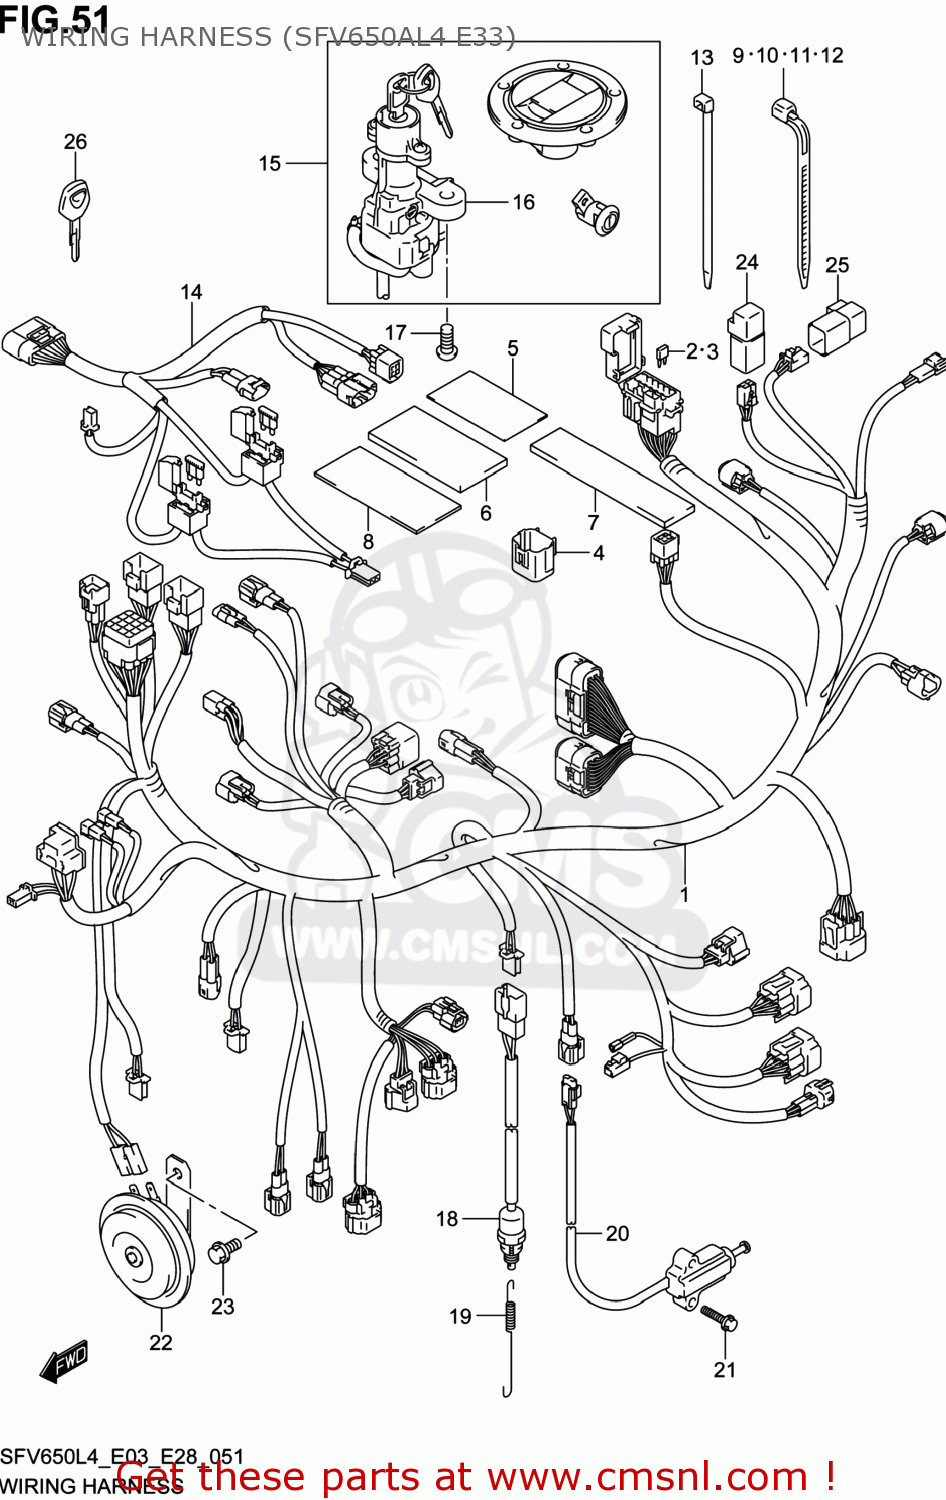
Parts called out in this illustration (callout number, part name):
1	HARNESS,WIRING
2	FUSE(10A)
3	FUSE(15A)
4	CAP,TS
5	TAPE,WIRING HARNESS(28X50X0.13
6	PROTECTOR(30X60X3)
7	PROTECTOR
8	PROTECTOR(20X90)X1.0
9	CLAMP(L:95)
10	CLAMP(L:125)
11	CLAMP(L:165)
12	CLAMP(L:190)
13	CLAMP(L:145)
14	WIRE,ABS LEAD
15	LOCK SET
16	LOCK ASSY,STEERING
17	BOLT(8X20)
18	SWITCH ASSY,STOP LAMP
19	SPRING
20	SWITCH ASSY,SIDE STAND
21	BOLT
22	HORN ASSY
23	BOLT
24	RELAY ASSY
25	RELAY ASSY
26	KEY,BLANK
